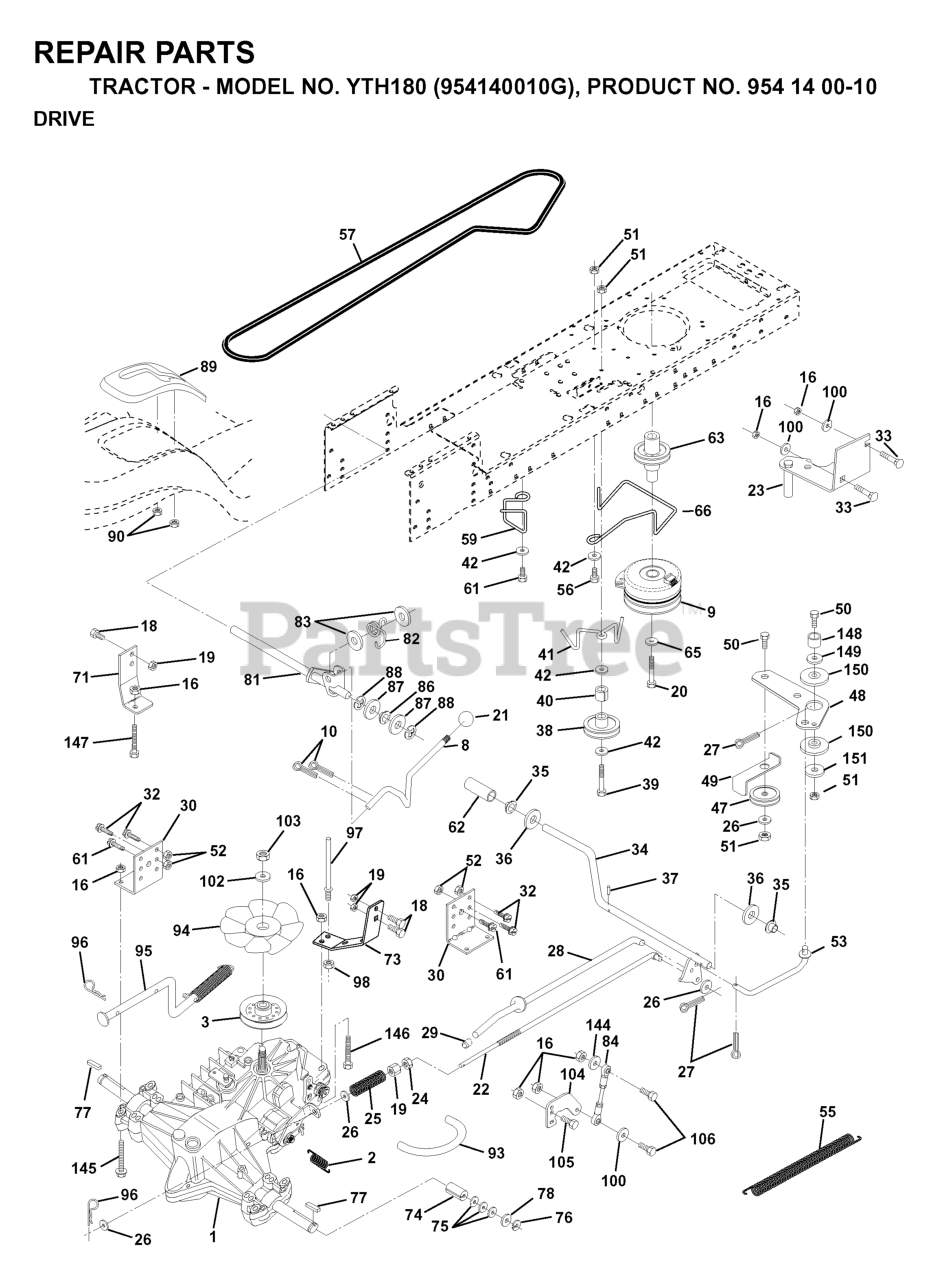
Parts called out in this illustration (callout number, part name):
1	TRANSAXLE ASSEMBLY
2	SPRING BRAKE
3	PULLEY, TRANSAXLE
8	ROD SHIFT FENDER
9	ELECTRIC CLUTCH
10	PIN COTTER
16	NUT.71038.31-18.HEX.NYLOCK
19	NUT
20	BOLT HEX
21	KNOB.DELUXE.(PISTOL.GRIP).BLAC
22	ROD BRAKE HYDRO
23	BRACKET, ASM CLUTCH MTG
24	NUT
25	SPRING ROD LT
26	WASHER
27	COTTER PIN
28	ROD BRAKE PARK LT
29	PLUNGER CAP
30	BRACKET TRANSAXLE
32	BOLT
33	RP BOLT 5/16-18 X3/4 ZN/YEL GR
34	SHAFT, FOOT PEDAL
35	BEARING.NYLON
37	DRIVE PIN
38	FLAT IDLER PULLEY
42	WASHER
47	IDLER PULLEY
48	BELLCRANK, CLUTCH
49	RETAIN BELT
50	BOLT
52	LOCKNUT
53	LINK, CLUTCH LT
55	SPRING, RETURN LT
57	DRIVE BELT, LTH & YTH TRACTORS
59	KEEPER CENTER SPAN
61	SCREW
62	COVER, PEDAL (1 2)
63	PULLEY, CLUTCH ELECT EVX
65	LOCKWASHER
66	KEEPER BELT ENGINE
71	STRAP LH TORQUE
73	STRAP TORQUE RH HYDRO
74	SPACER SPLIT
77	SQUARE KEY
81	SHAFT ASSY
82	SPRING,TORSION
83	WASHER
89	SHIFT CONSOLE
90	NUT.PUSH.3/16
93	LINE FUEL HYD 4"
94	FAN 7" HYDRO
95	CONTROL ARM, BYPASS HYDRO
96	RETAINER M
97	KEEPER BELT RH
100	WASHER M
103	NUT.HEX.1/2-20
104	CONTROL ARM
106	BOLT.5/16-18X1-1/4 FULL.THREAD
144	Washer 11/32 x 5/8 x 16 Ga SD
146	Bolt Hex Flanged 5/16-18 Unc x 2
147	Bolt Hex Flanged 5/16-18 Unc x 2
149	SPACER RETAINER
150	BUSHING NYLON COLLERED
151	WASHER 12/32X2X10GA
